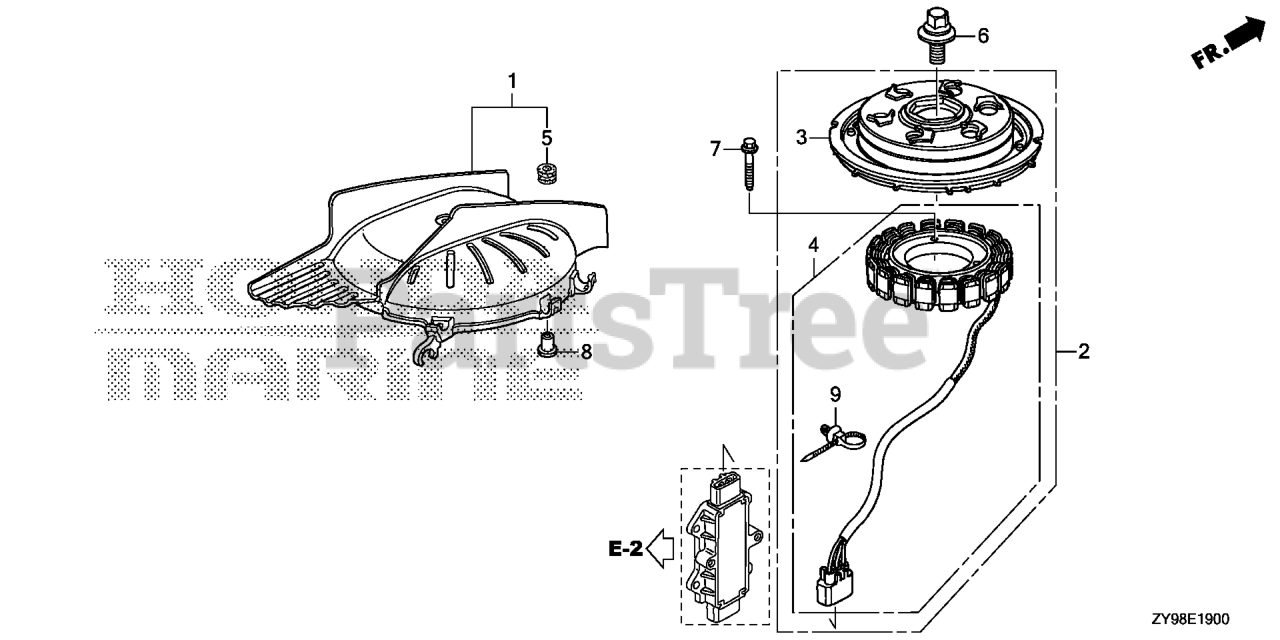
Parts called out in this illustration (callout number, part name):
1	COVER ASSY., ALTERNATOR
2	ALTERNATOR ASSY.
5	GROMMET, CASE (LOWER)
6	BOLT-WASHER (14X36)
7	BOLT, FLANGE (6X32) (CT200)
7	BOLT (6X32) (CT200)
8	COLLAR, MODULE IGNITION CONTROL CASE (CDI)
8	COLR, CDI UNIT CASE
8	COLLAR (12X6.5)
9	CLIP, HARNESS BAND (96.9MM) (NATURAL)
